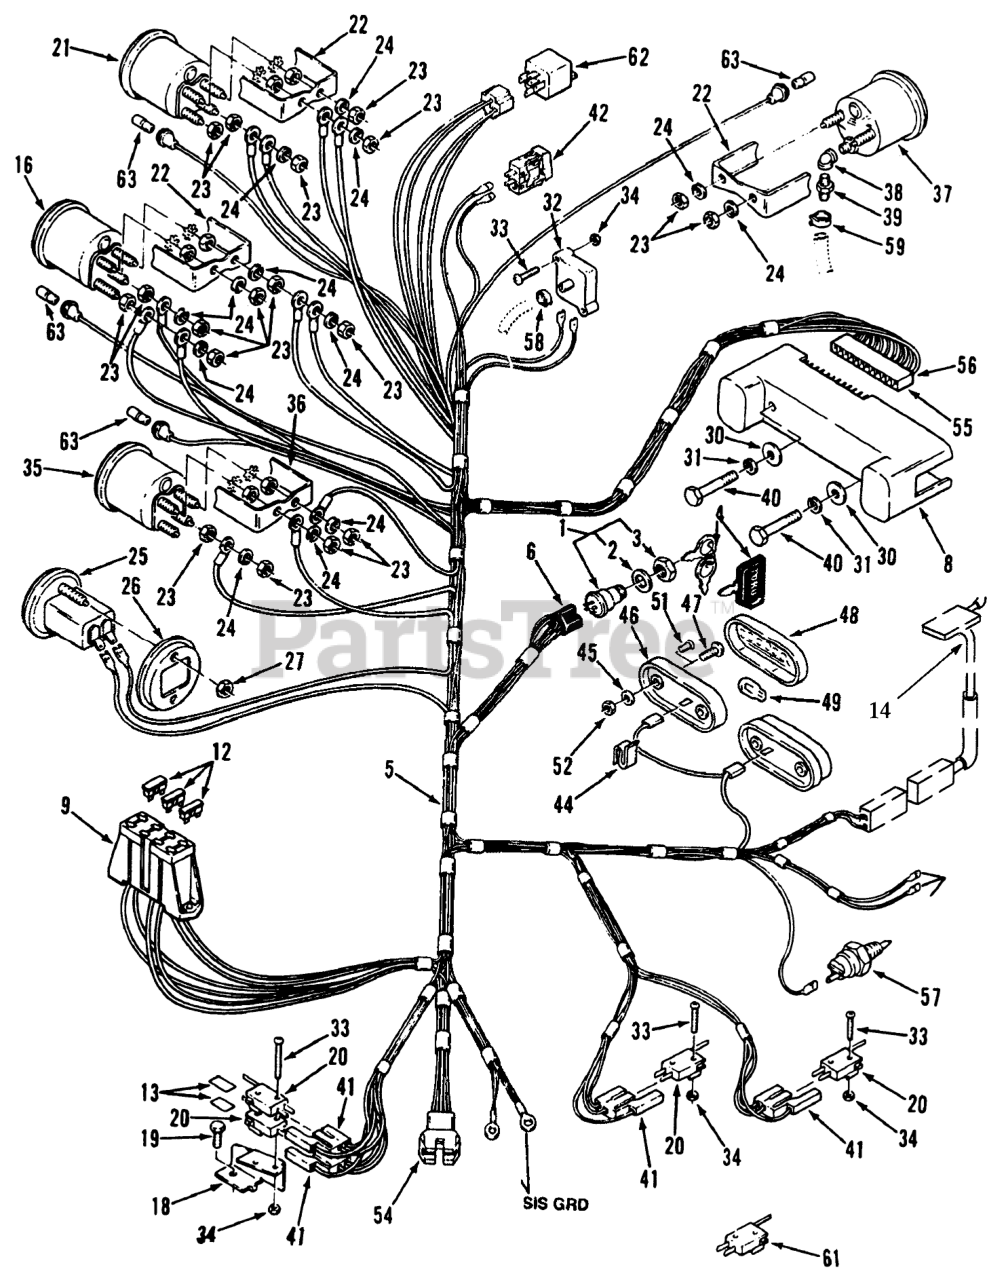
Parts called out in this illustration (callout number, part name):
1	SWITCH-IGNITION
2	Washer
4	Ignition Key
5	WIRING-HARNESS & DIA
6	CONNECTOR-5 WAY-SERV
8	CIRCUIT-BRD 8 LIGHT
9	FUSE-HOLDER 4 WAY
12	FUSE-10 AMP
13	BARRIER - SWITCH
14	SWITCH-SEAT
16	Gauge-Fuel (Includes Item 22)
18	Support-Switch
19	Bolt
20	SWITCH
21	Voltmeter (Includes Item 22)
22	CLAMP-MOUNTING
23	Nut
24	Washer-Lock #10
25	Hourmeter (Includes Item 26)
26	Bracket-Mountin
27	Nut
30	WASHER-FLAT
31	WASHER-LOCK
32	SENSOR-AIR CLEANER
33	Screw
34	NUT HEX 4-40 ELAST
35	Tachometer (Includes Item 36)
36	MOUNTING-BRACKET
37	Gauge-Vacuum (Includes Item 22)
38	ELBOW
39	FITTING STRAIGHT
40	SCREW
40	ELBOW-45 DEG
41	CONNECTOR BODY
42	Light Switch
44	SPEED CLIP
45	WASHER-LOCK, INT
46	BASE-TAIL LIGHT
47	Screw
48	LENS-TAIL LIGHT
49	LIGHT BULB
51	NUT-HEX
52	NUT-HEX
54	9-CIRCUIT CAP
55	Connector-Male
56	Terminal
57	SENSOR-HYDRO OIL HOT
58	CLAMP-HOSE 5/16"
59	Clamp
61	SWITCH - CLUTCH
62	RELAY
63	LAMP-MINIATURE GE 53X
